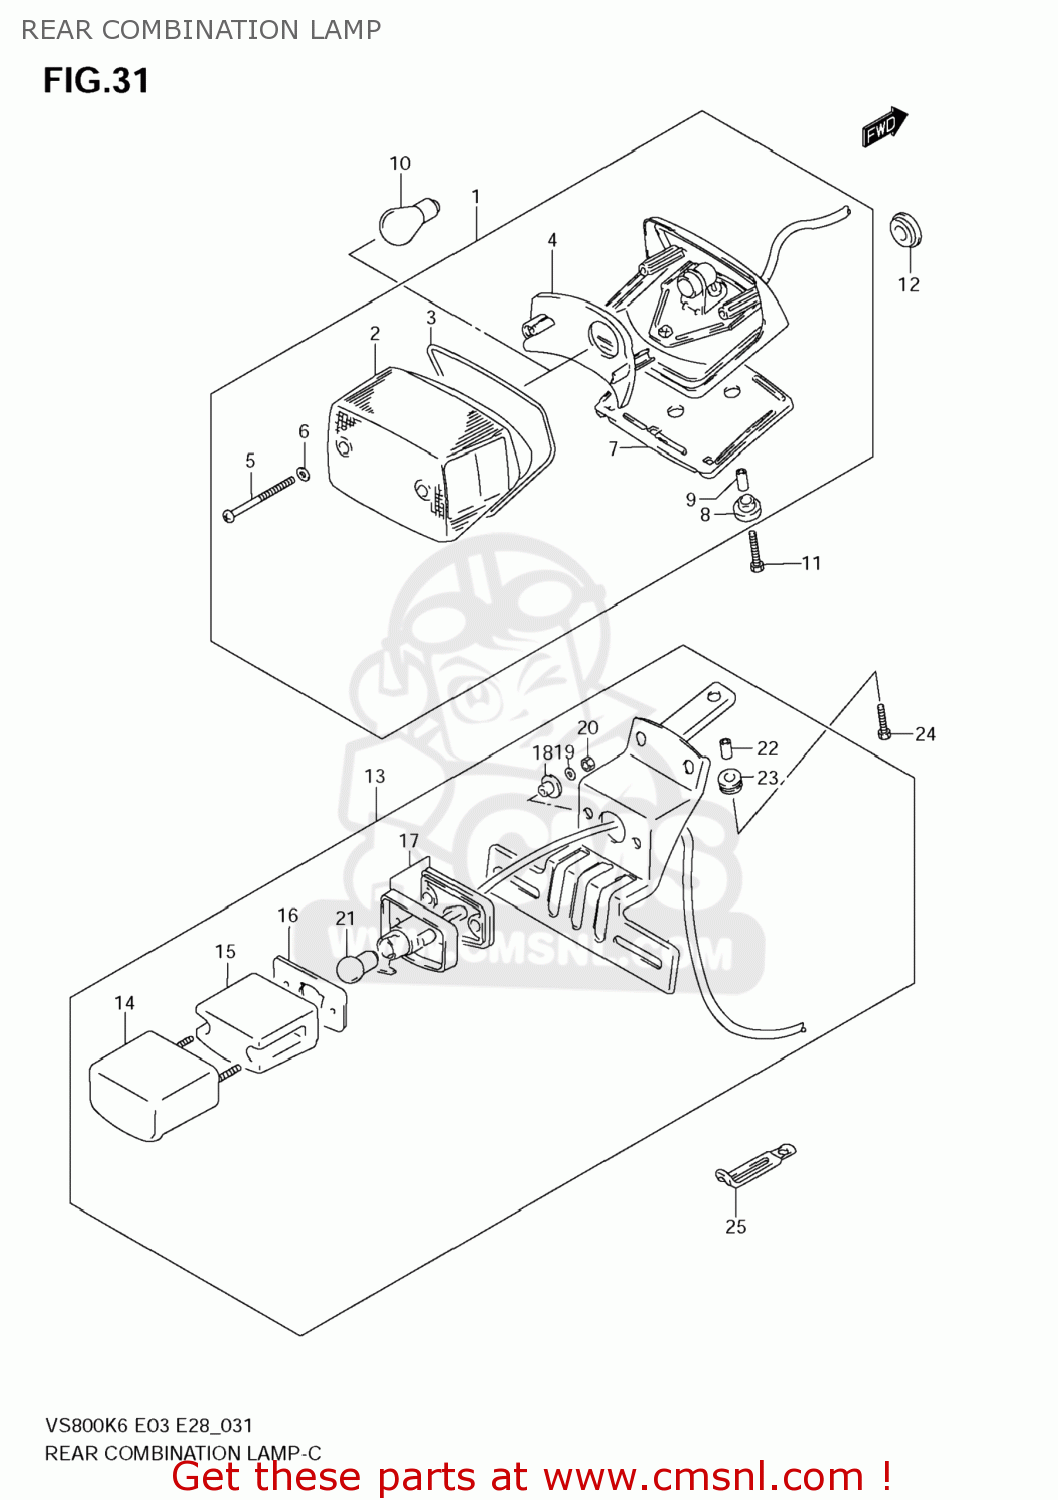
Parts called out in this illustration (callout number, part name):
1	LAMP ASSY,RR COMBINATION
2	LENS
3	GASKET (NAS)
4	REFLECTOR
5	SCREW
6	GASKET (NAS)
7	CUSHION
8	CUSHION
9	SPACER
10	BULB(12V21/5W,BF141-49642A)
11	BOLT(6X25)
12	GROMMET
13	LAMP ASSY,LICENSE
14	COVER,LENS
15	LENS
16	GASKET,LICENSE LAMP (NAS)
17	HOUSING,LICENSE LAMP
18	SPACER
19	WASHER,LOCK
20	NUT
21	BULB(12V5W,BF150-40160A)
22	SPACER
23	CUSHION
24	BOLT(6X20)
25	CLAMP(L:45)
